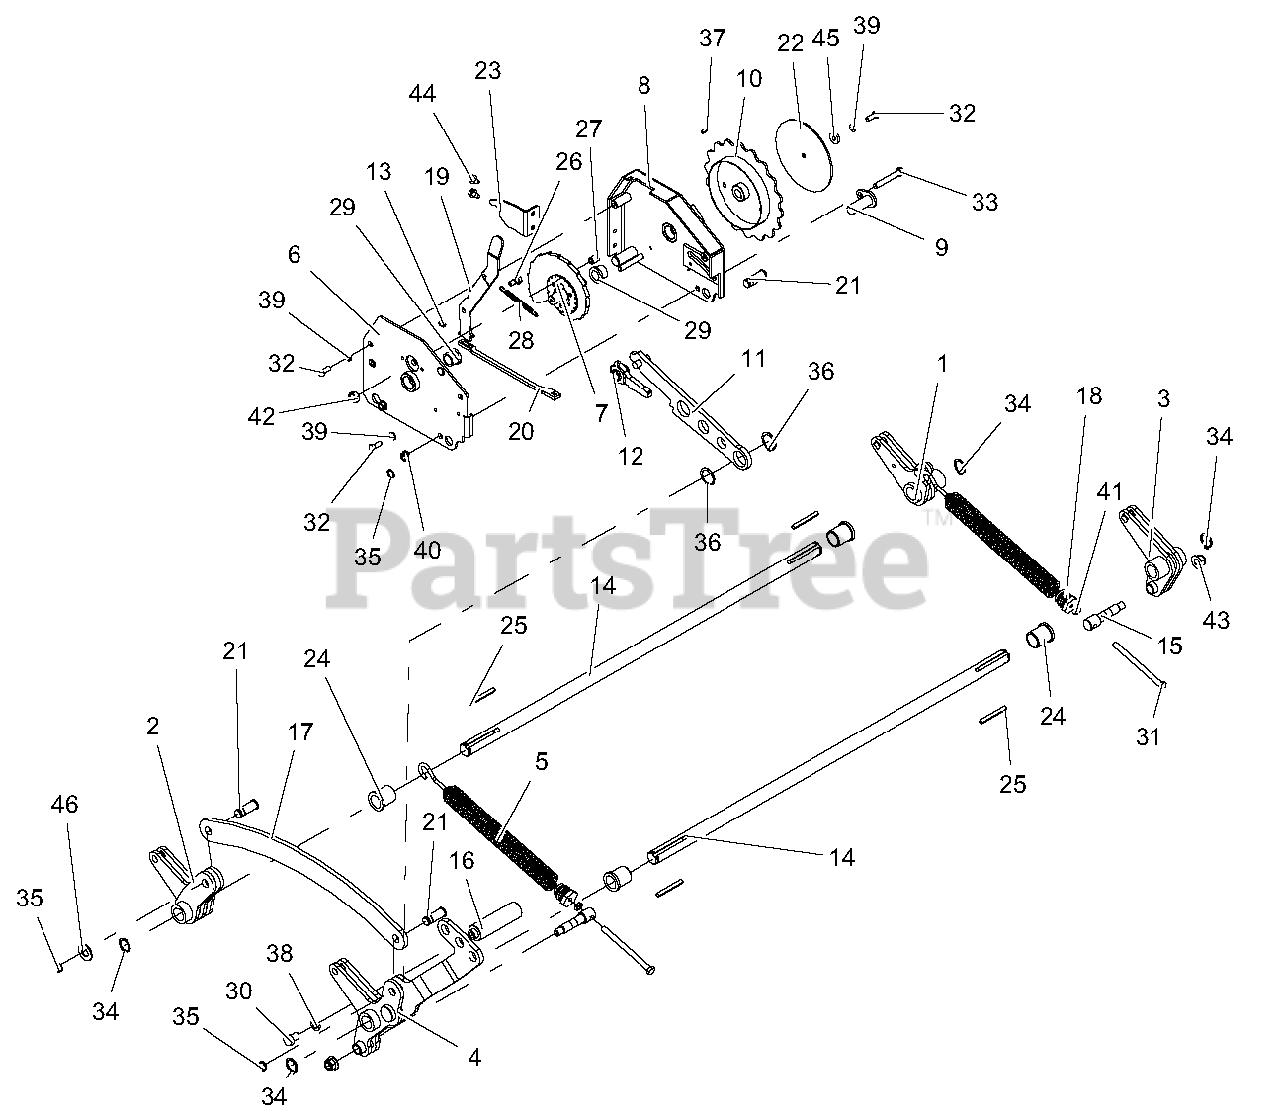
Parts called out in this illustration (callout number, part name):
1	WLDMT, LEFT REAR LIFT
2	WLDMT, RIGHT REAR LIFT-BLACK
3	WLDMT, LEFT FRONT LIFT
4	WLDMT, LIFT PEDAL-BLACK
5	SPRG, DECK LIFT
6	WLDMT, HOC OUTER-RED
7	WLDMT, CAM HOC
8	WLDMT, HOC INNER
9	WLDMT, PIN
10	WLDMT, DIAL, HOC
11	WLDMT, HOC LINK-BLACK
12	WLDMT, LOCK PAWL
13	WAVE WASHER .390X.655X.110
14	SHAFT, FRONT MOWER LIFT
15	TRUNION, SPRG
16	PEDAL, LIFT
17	LIFT, LINK
18	PLUG, SPRG
19	LEVER, TRANSPORT LOCK-BLACK
20	LINK, TRANSPORT LOCK
21	PIN, CLEVIS .625 SNAP RING
22	PLATE, DIAL-RED
23	GUARD, DECK LIFT
24	BSHG-FLG 1.00X1.25X1.5X1.5
25	KEY, SQ .25 X 2.50 X .25 SAE
26	BOLT, SHLDR .38-16 x .437 HEX YZ
27	BALL SPRING PLUNGER, .500-13
28	SPRG, EXTENSION
29	BUSHING, .750 X 1.00 X .750
30	BLT-HEX .50-13X.75 GR5 YWZC
31	BLT-HEX .38-16X5.00 GR5 YWZC
32	BLT-HEX .31-18X.75 GR5 YWZC
33	BLT-HEX .38-16X2.50 GR5 YWZC
34	RG-RTNG-EXT 1.00X.078
35	RG-RTNG-EXT .625x.050
36	RG-RTNG-EXT 1.25x.050
37	KEY-SQ .188X.188X.375
38	@WSHR-LK .50X.125 REG YWZC
39	@WSHR-LK .31X.078 REG YWZC
40	NUT, LK-CTR-FLG .38-16 YWZC
41	NUT, JAM .375-16 YWZC
42	NUT, JAM .500-13 YWZC
43	NUT-LK-NYL-FLG .50-13 YWZC
44	SCR-TAP .31-18X.50 HWH TR YWZ
45	WSHR-FL-STL .328X.87X.179 YWZC
46	@WSHR-FL-STL.656X1.31X.095 YWZ
